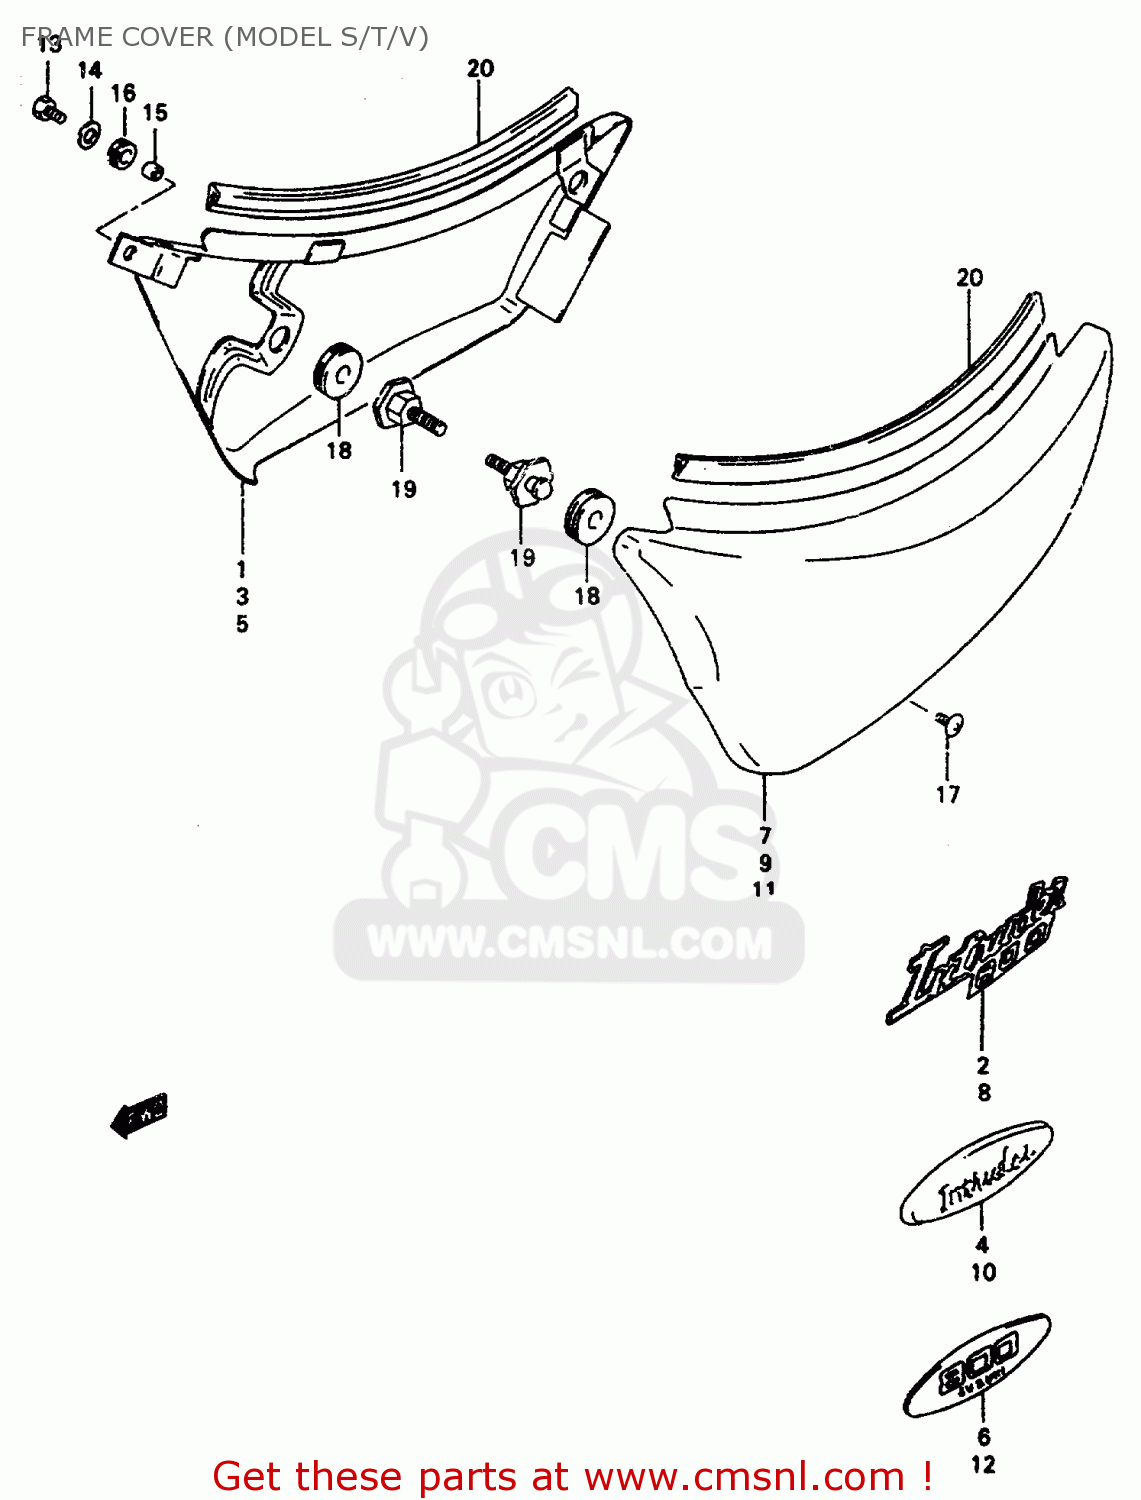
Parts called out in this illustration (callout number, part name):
1	COVER ASSEMBLY,FRAME,RIGHT
2	EMBLEM,FRAME COVER
3	COVER,FRAME,R(MAROON)
4	EMBLEM,FRAME C
5	COVER,FRAME,R(RED)
6	EMBLEM,FRAME COVER
7	COVER ASSEMBLY,FRAME,LEFT
8	EMBLEM,FRAME COVER
9	COVER,FRAME,L(GREEN)
10	EMBLEM,FRAME C
11	COVER,FRAME,L(RED)
12	EMBLEM,FRAME COVER
13	BOLT
14	WASHER(6.5X18X1.6)
15	SPACER (6.1X8X5.2)
16	CUSHION
17	SCREW 6X10
18	CUSHION
19	BOSS,FRAME COVER
20	MOLDING, FRAME COVER
